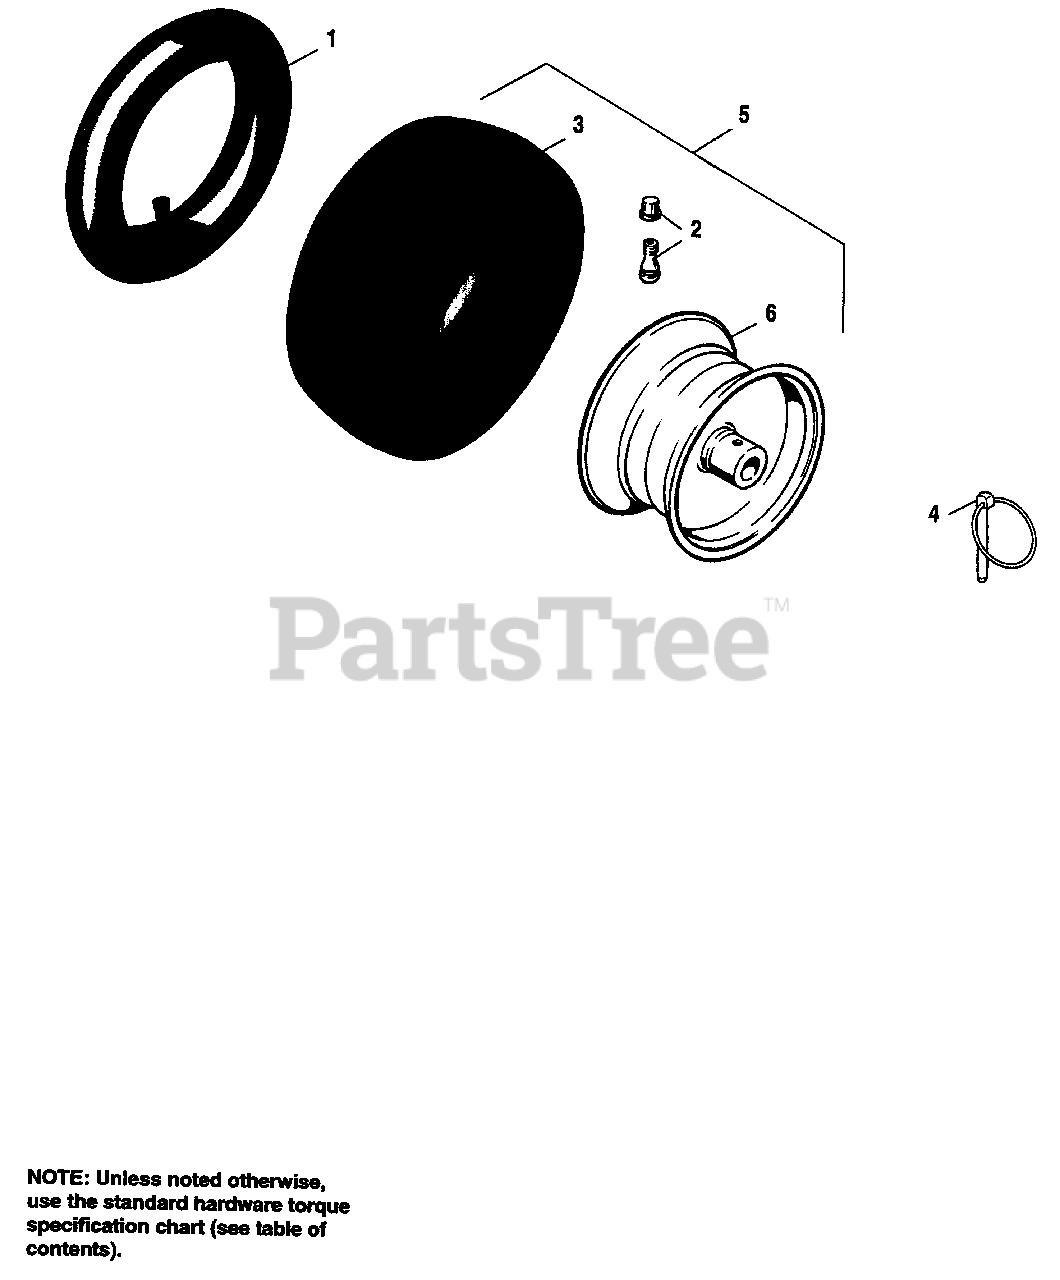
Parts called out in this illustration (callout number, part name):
1	TUBE, 4.80/4.00-8
2	VALVE STEM & CAP
3	TIRE, Snow Hog
5	WHEEL & TIRE ASSY. (Incl. Ref. Nos. 2, 3 & 6)
6	HUB, Wheel R.H., 3-3/4 Wide 8 Diameter 3/4 ID
